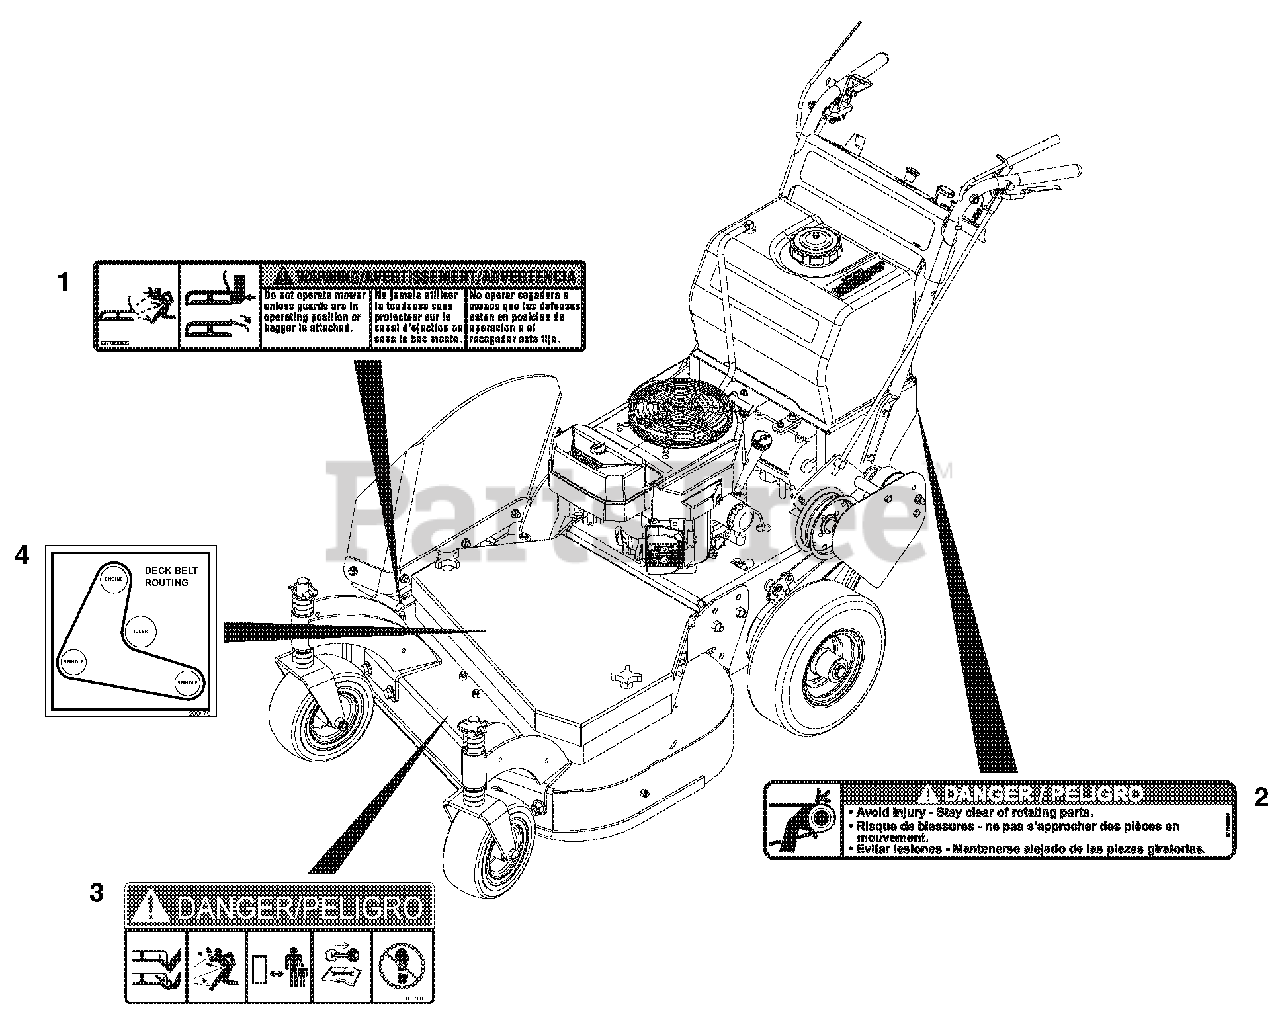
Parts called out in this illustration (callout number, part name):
1	Decal, Warning
2	Decal, Danger-Belt Rotating
3	Decal, Mower Pan Danger
4	Decal, Deck Belt Routing (988143, 144)
